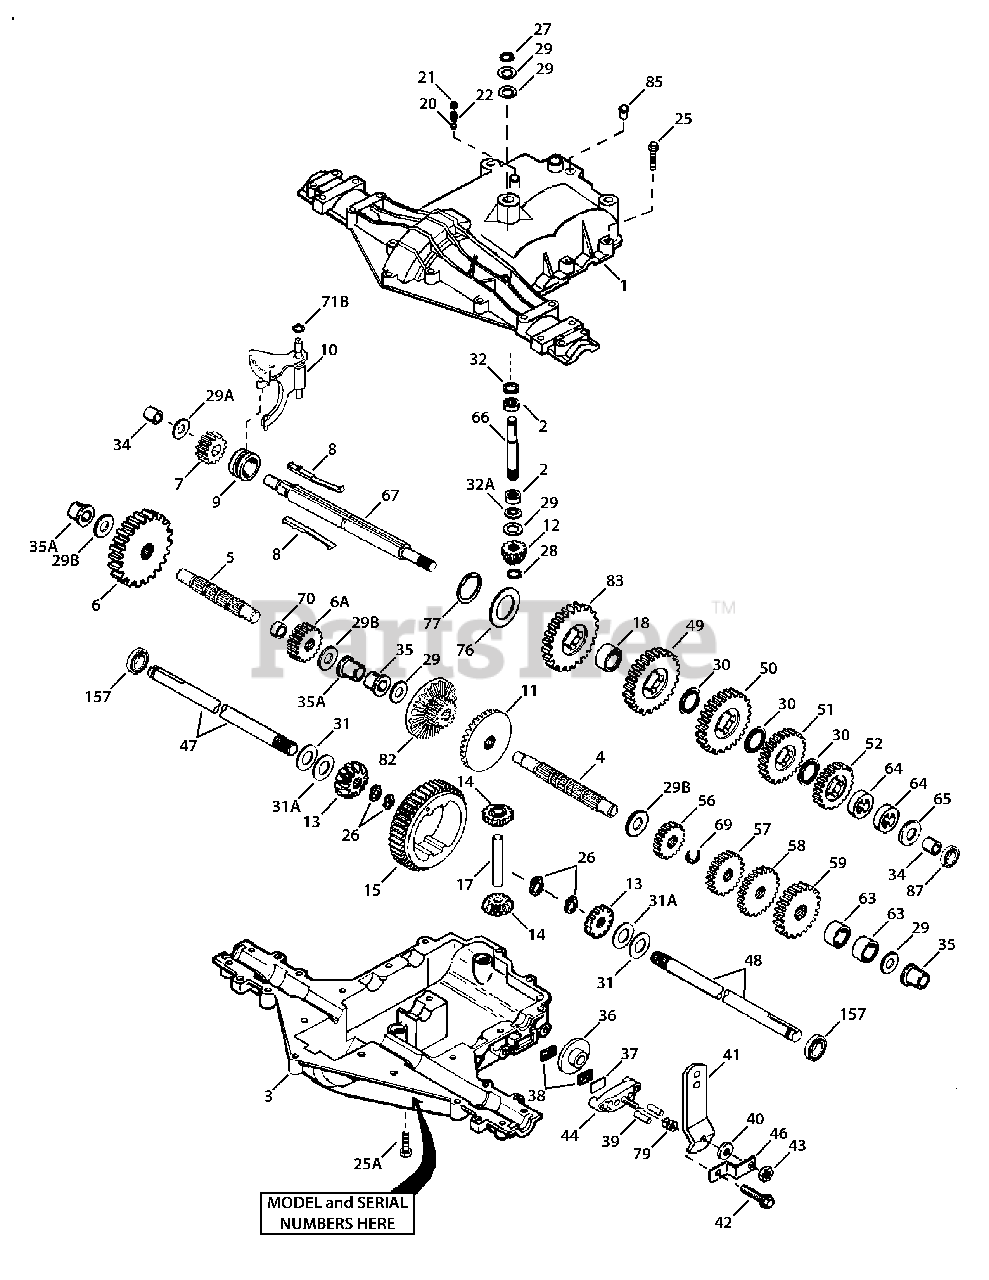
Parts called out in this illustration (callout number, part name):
1	Transaxle Cover
2	Needle Bearing (1/2" long)
3	Transaxle Case
4	Countershaft
5	Output Shaft
6	Spur Gear (38T-PM/SER)
6A	Spur Gear (15T-PM/SER)
7	Spur Gear (11T-PM/SER)
8	Shift Key Set (Qty. 2)
9	Shift Collar
10	Shift Rod & Fork Assembly
11	Bevel Gear (30T-PM)
12	Input Bevel Pinion (13T-PM)
13	Bevel Gear 13T (Incl. ref. 13 & 14)
14	Bevel Gear 13T (Incl. ref. 13 & 14)
15	Ring Gear (43T)
18	Spacer (1.130" x .695")
20	Ball (Stainless Steel 5/16" dia.)
21	Screw, 3/8-16 x 3/8"
25	Screw, 1/4-20 x 1-1/4"
25A	Screw, 1/4-20 x 1-3/8"
26	Retaining Ring-package of 2
27	Retaining Ring
28	Retaining Ring
29	Washer .627" ID .031"
29A	Thrust Washer (.563" ID x .031")
29B	Thrust Washer (.762" ID X .031")
30	Shift Washer (Cupped)
31	Washer .750" ID .56"
31A	Washer .750" ID .062
32	Oil Seal 5/8"
32A	O Ring (.823" OD)
34	Bushing (.563")
35	Flanged Bushing (.625" ID)
35A	Flanged Bushing (.751" ID)
36	Brake Disk
37	Brake Pad Plate
38	Brake Pad (pkg. of 2)
39	Dowel Pin .3125" x .750"
40	Washer .312" ID .059"
41	Brake Lever
42	Screw 1/4-20 x 1-3/8"
43	Lock Nut 5/16-24
44	Brake Pad Holder
47	Axle (10.719" long) (Incl. 26)
48	Axle (15.312" long) (Incl. 26)
49	Spur Gear (27T-PM/IC)
50	Spur Gear (22T-PM/IC)
51	Spur Gear (19T-PM/IC)
52	Spur Gear (16T-PM/IC)
56	Spur Gear (13T-PM/SER)
57	Spur Gear (18T-PM/SER)
58	Spur Gear (21T-PM/SER)
59	Spur Gear (24T-PM/SER)
63	Countershaft Spacer 1-1/8" x 3/8’’
64	Brake Shaft Spacer 1-3/8" x 3/8’’
65	Washer .563" ID .062
66	Input Shaft
67	Brake Shaft
69	Retaining Ring (.75" x .042")
70	Spacer (.890")
76	Flat Washer (1.128" ID x .058")
77	Retaining Ring (1.125" x .050")
82	Bevel (30T) & Spur Gear
83	Spur Gear (27T-PM/IC)
85	Oil Fill Plug
87	Oil Seal 9/16" ID
157	Oil Seal 3/4" ID
